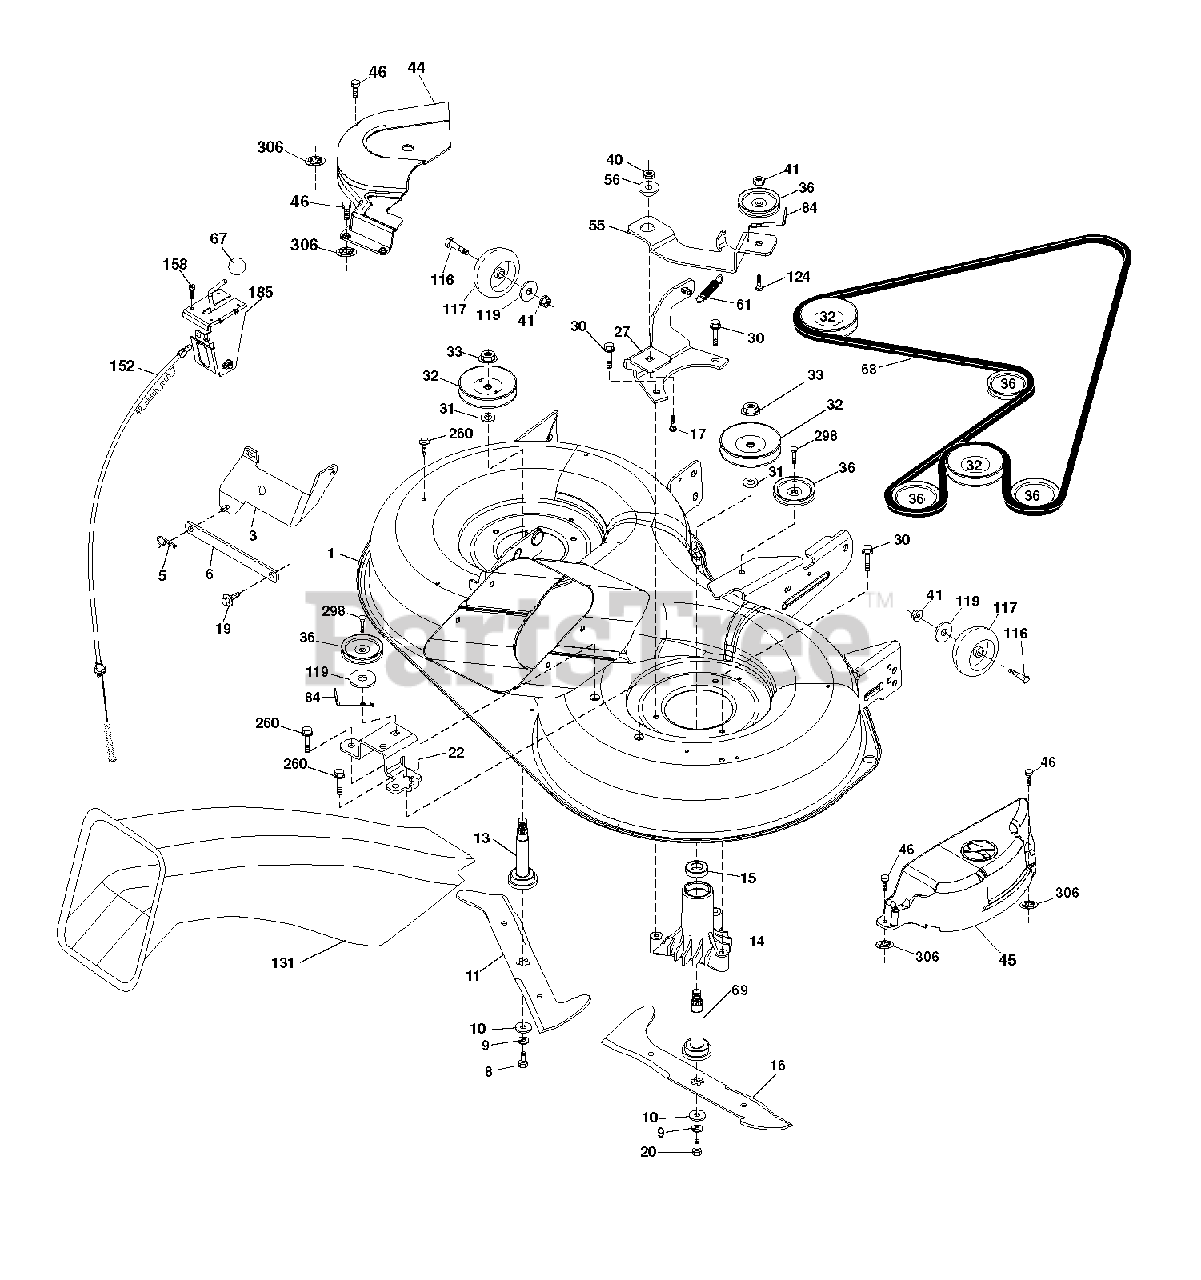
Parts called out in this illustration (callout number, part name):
1	DECK.WLDT.97.CRD.2GWB
3	BRACKET.ASM.BAR.SWAY.CHASS
5	RETAINER-SPRNG RB
6	BAR SWAY
8	Bolt, 3/8-24 X 1.25 Gr8
9	LOCKWASHER
11	BLADE.3N1.LH.CRD.97
13	SHAFT ASM VENT
16	BLADE.3N1.RH.CRD.97
17	BOLT.3/8-14X1.25
19	BOLT SHD 5/16-18
20	BOLT.3/8-24X1.25GR8. LHTHRD
22	BRACKET.SUPT.IDLER.REAR.RH
27	BRACKET.ASM.SUSP.REAR.RH.
30	SCREW, WASHER HEAD
31	WASHER.SPACER.MANDREL
32	PULLEY MANDREL
33	NUT.FLANGE.LOCK.TOP
36	PULLEY.IDLER.4.25
40	LOCKNUT
41	NUT LOCK FLG 3/8-16 UNC
44	OVER.MANDREL.LH.CRD
45	COVER.MANDREL.RH.97.CRD
46	SCREW.1/4-20X5/8
56	SPACER.RETAINER.MOWER
67	KNOB T (3/8 HOLE)
68	BELT.DRIVE.CRD.97.2010
69	SHAFT.ASM.W/LWR.BRG.RH.THREAD
84	KEEPER, BELT IDLER
116	BOLT.SHOULDER.3/8-16X3-5/8
117	WHEEL. GUAGE RALLY
124	BOLT.3/8-16X1.50
158	SCREW
185	HEAD ASM. CABLE CLUTCH
260	SCREW 3/8-16X1/2
298	SCREW LT
